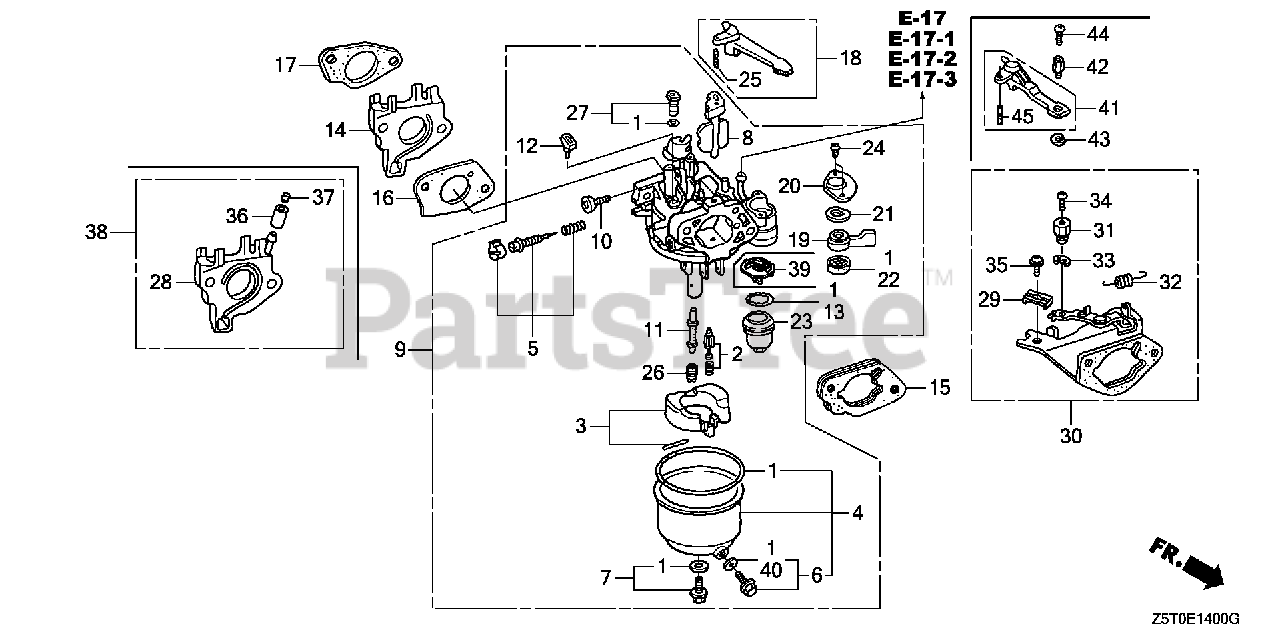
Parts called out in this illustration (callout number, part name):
1	GASKET SET (INCLUDE 16173-001-004) (INCLUDES 16173-001-004)
2	VALVE SET, FLOAT
3	FLOAT SET (CARBURETOR NO.)
4	CHAMBER SET, FLOAT
5	SCREW SET (Honda Code 4219879). (CARBURETOR NO.)
6	SCREW SET, DRAIN (Honda Code 1672187). (CARBURETOR NO.)
7	SCREW SET
8	CHOKE SET (CARBURETOR NO.)
9	CARBURETOR ASSY. (BE85Q A)
10	SCREW, THROTTLE STOP
11	NOZZLE, MAIN (CARBURETOR NO.)
12	COLLAR, SET
13	GASKET, FUEL STRAINER CUP
14	INSULATOR, CARBURETOR
15	SPACER, CARBURETOR
16	GASKET, CARBURETOR
17	GASKET, INSULATOR Use up to Engine SN 2949254.
18	LEVER, CHOKE (STD)
19	LEVER, VALVE
20	PLATE, LEVER SETTING (CARBURETOR NO.)
21	SPRING, PETCOCK LEVER (CARBURETOR NO.)
22	GASKET, VALVE
23	CUP, FUEL STRAINER
24	SCREW, PAN (3X6)
25	PIN, SPRING (2X12)
26	JET, MAIN (#88) Use up to Engine SN BE81B B.
26	JET, MAIN (#90) Use from Engine SN BE81B C.
26	JET, MAIN (#92)
27	JET SET, PILOT (#45)
